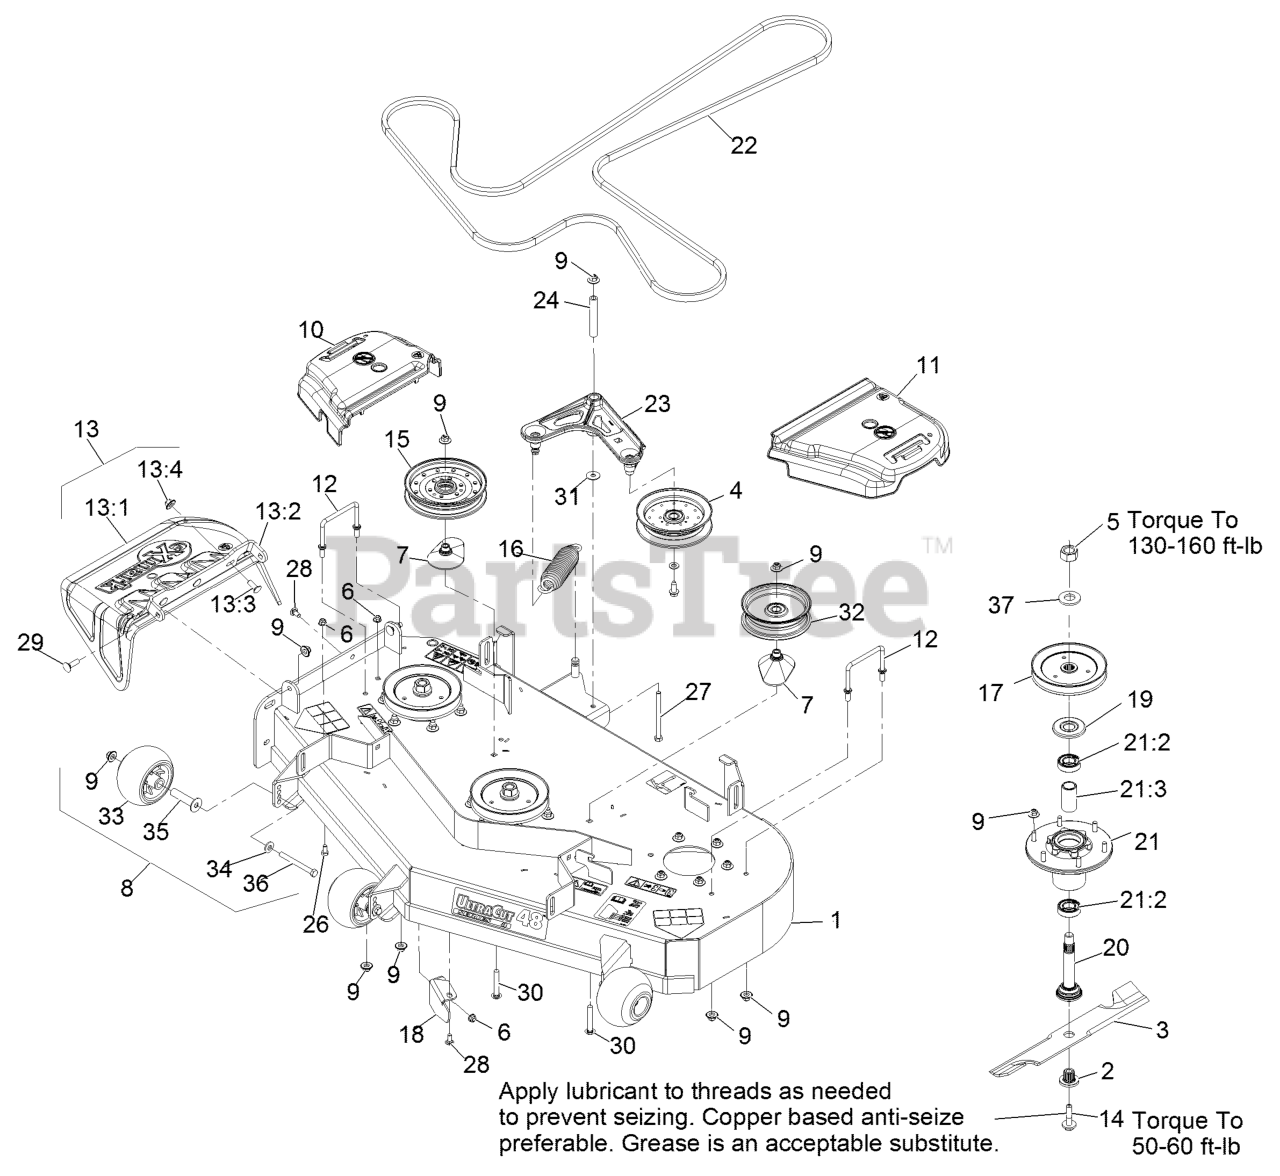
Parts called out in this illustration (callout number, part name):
1	ASM-DECK W/DECALS 48
2	BUSHING,SPLINED
5	NUT-HEX
6	NUT-HF, NI
7	SPACER-PULLEY
8	KIT, ANTI-SCALP ROLLER
9	Nut-Nyloc 3/8-16 Flg
10	COVER-BELT, RH
11	COVER-BELT, LH
12	WIREFORM-COVER
13	ASM,DISCHARGE CHUTE
13:1	CHUTE,DISCHARGE
13:2	BRACKET,DISCHARGE CHUTE
13:3	SCREW-CARR
13:4	Nut-Nyloc 3/8-16 Flg
14	SCREW,SEMS 1/2-20 X 2.19
16	SPRING-EXTENSION
17	SHEAVE,BLADE DRIVE 5.90
18	BAFFLE,DISCHARGE 483
19	GUARD,BEARING TOP .989
20	ASM-SPINDLE AND SEAL
21	ASM-CUTTER HSG WITH BEARINGS
21:2	BEARING-BALL
21:3	SPACER-BEARING
22	BELT-B154.88
23	IDLER ARM ASM
24	BUSHING
26	SCREW-HH
27	SCREW-HH
28	BOLT-CARR
29	BOLT-CARR
30	SCREW-CARR
32	IDLER-PULLEY, FLAT
33	ROLLER-SCALP, ANTI
34	WASHER-BELLEVILLE
35	AXLE, ROLLER
36	SCREW-HH 3/8-16 X 3 3/4 GR 8
